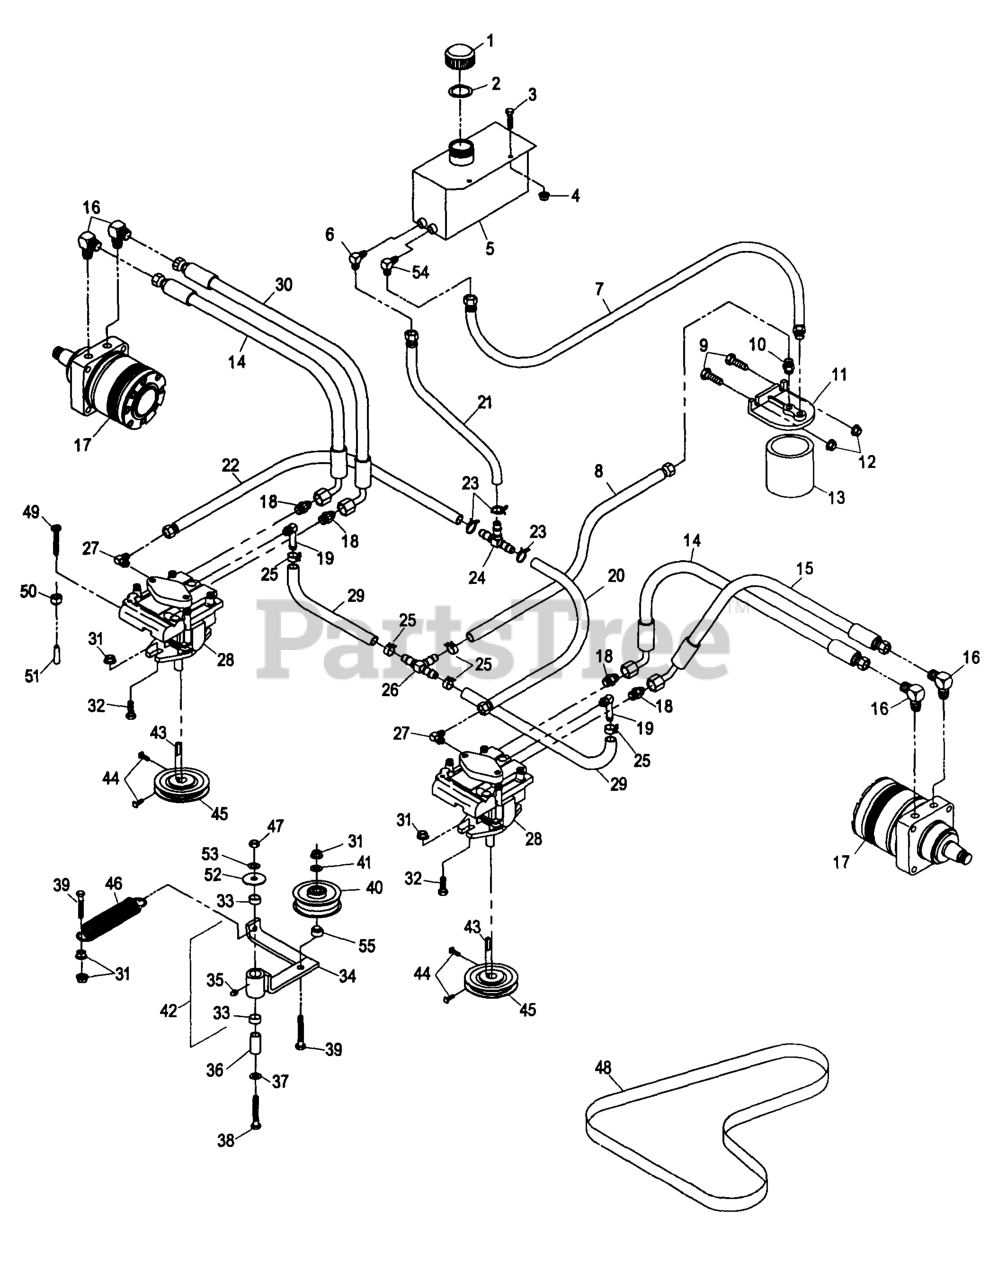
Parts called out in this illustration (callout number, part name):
2	GASKET-CAP, TANK
6	FITTING-ELBOW
10	FITTING-STRAIGHT
14	HOSE-FRONT
15	HOSE, LH REAR
16	FITTING-HYD, 90 DEG
17	MOTOR-WHEEL
18	FITTING-STRAIGHT
19	FITTING
20	HOSE ASM
22	HOSE ASM
23	CLAMP-HOSE
24	FITTING-TEE, HOSE
25	CLAMP-HOSE
26	FITTING-TEE, HOSE
27	FITTING-90 DEG
30	HOSE-REAR, RH
33	SLEEVE-BEARING
36	BUSHING
44	SCREW-SET
46	SPRING-EXTENSION
51	GRIP-VALVE, DUMP
54	FITTING-ELBOW
55	BUSHING-IDLER
